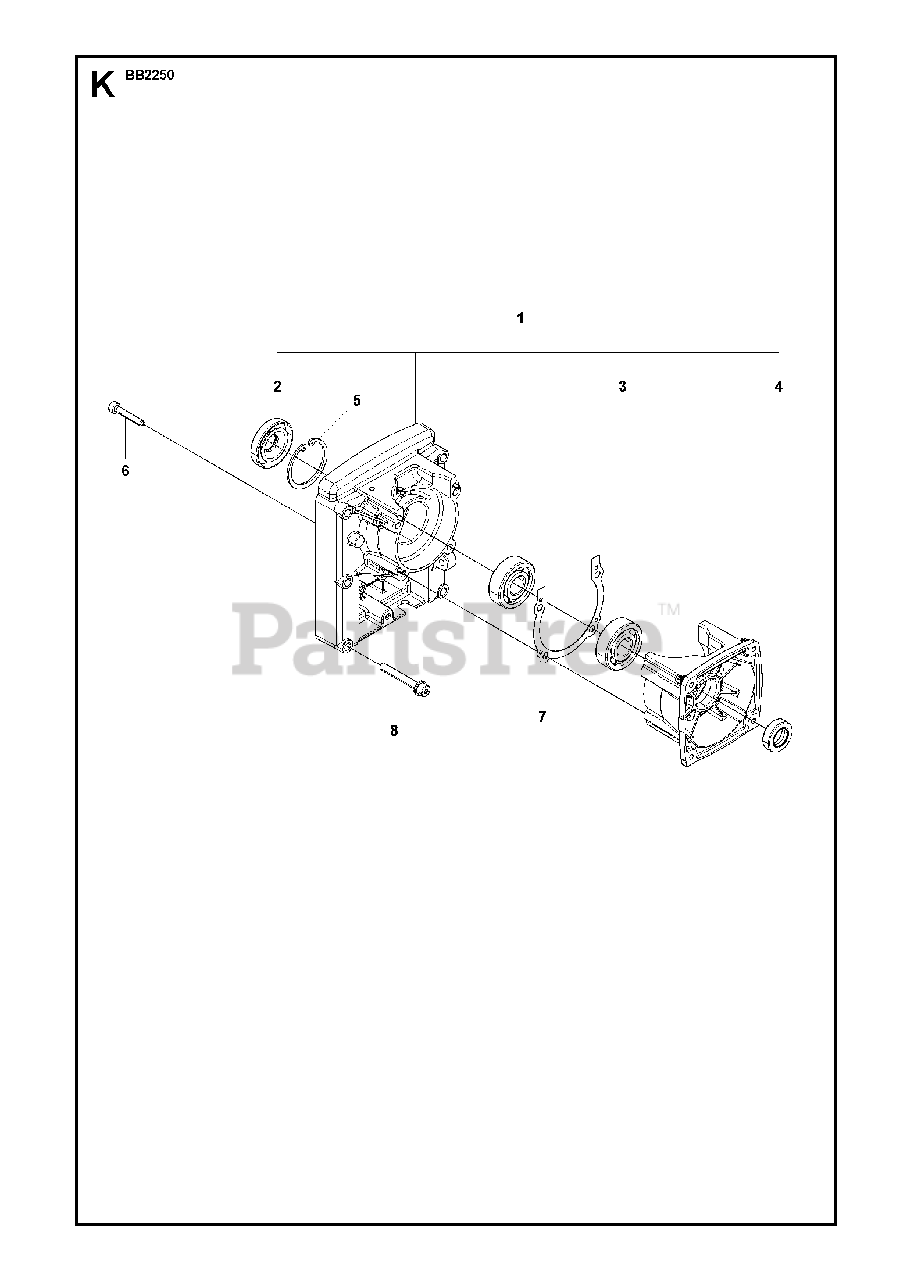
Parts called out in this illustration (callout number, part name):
1	CRANKCASE
2	SEALING
3	BEARING
4	SEALING
6	BOLT
8	RP_BOLT
